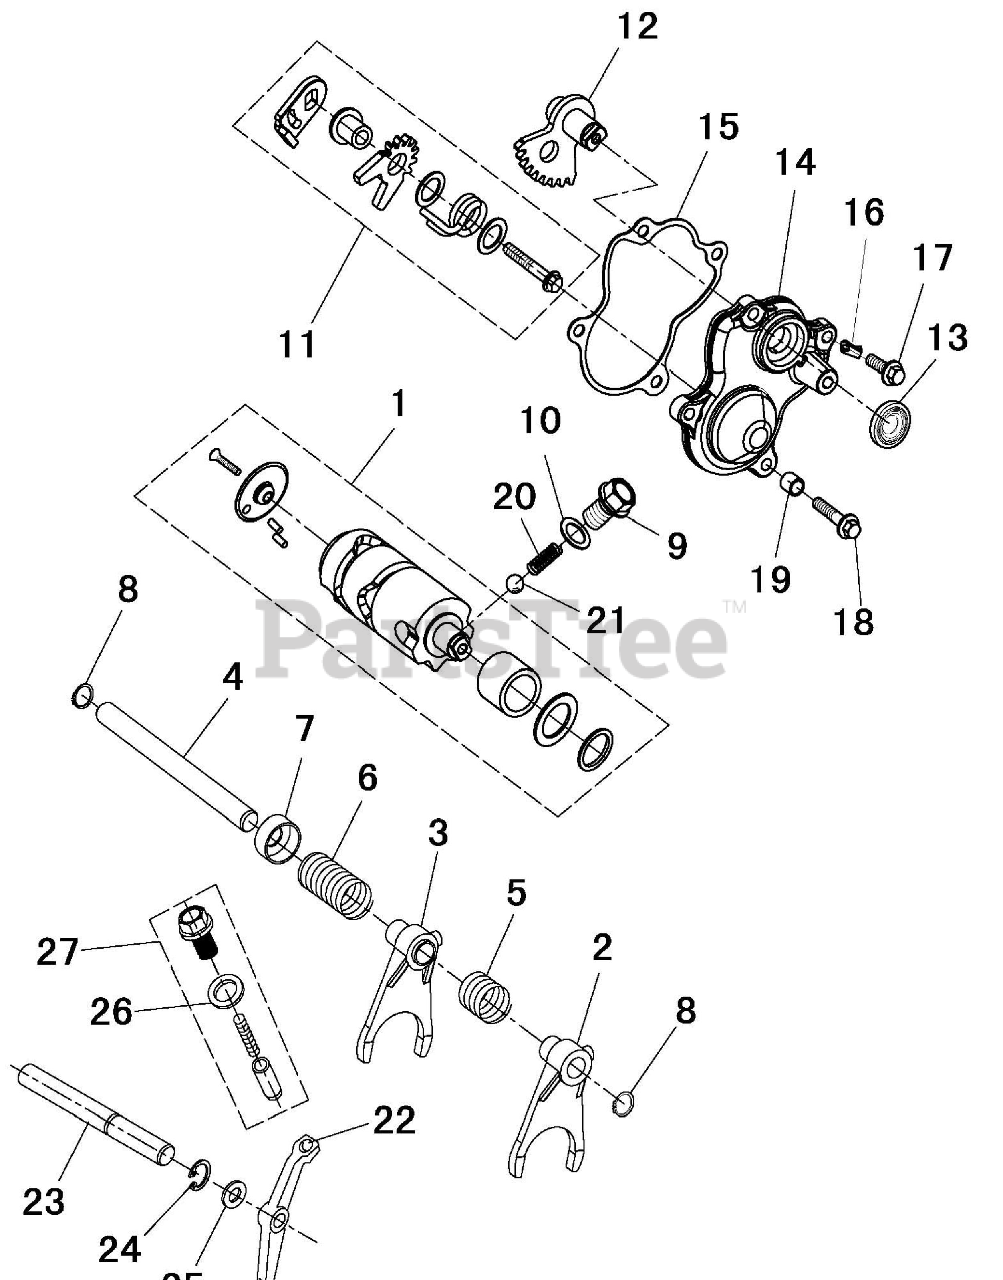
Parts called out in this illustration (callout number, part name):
1	SHIFT DRUM
2	Shifting Fork I
3	Shifting Fork II
4	Shift Rail
5	Spring, R gear
6	Spring,HL gear
7	Spring seat,Shift Rail
8	Circlip for shaft 12
9	Hollow Bolts M14x1.5x21
10	Copper Washer 14x21x1
11	Shift Dialing Plate Assy
12	Shiftshaft Assy
13	Oil Seal 15x25x5
14	Shiftshaft Cover
15	Gasket,Shiftshaft Cover
16	CLAMP
17	Hex flange bolts M6x20
18	Hex flange bolts M6x30
19	Pin,Dowel 8x12
20	Spring 24x1
21	Steel Ball 9.5
22	PARKING ARM
23	PARKING ARM SHAFT
24	Circlip for shaft 12
25	WASHER 12.3 x 20 x 1
26	Copper Washer 14x21x2
27	PARKING BOLT ASSEMBLY
